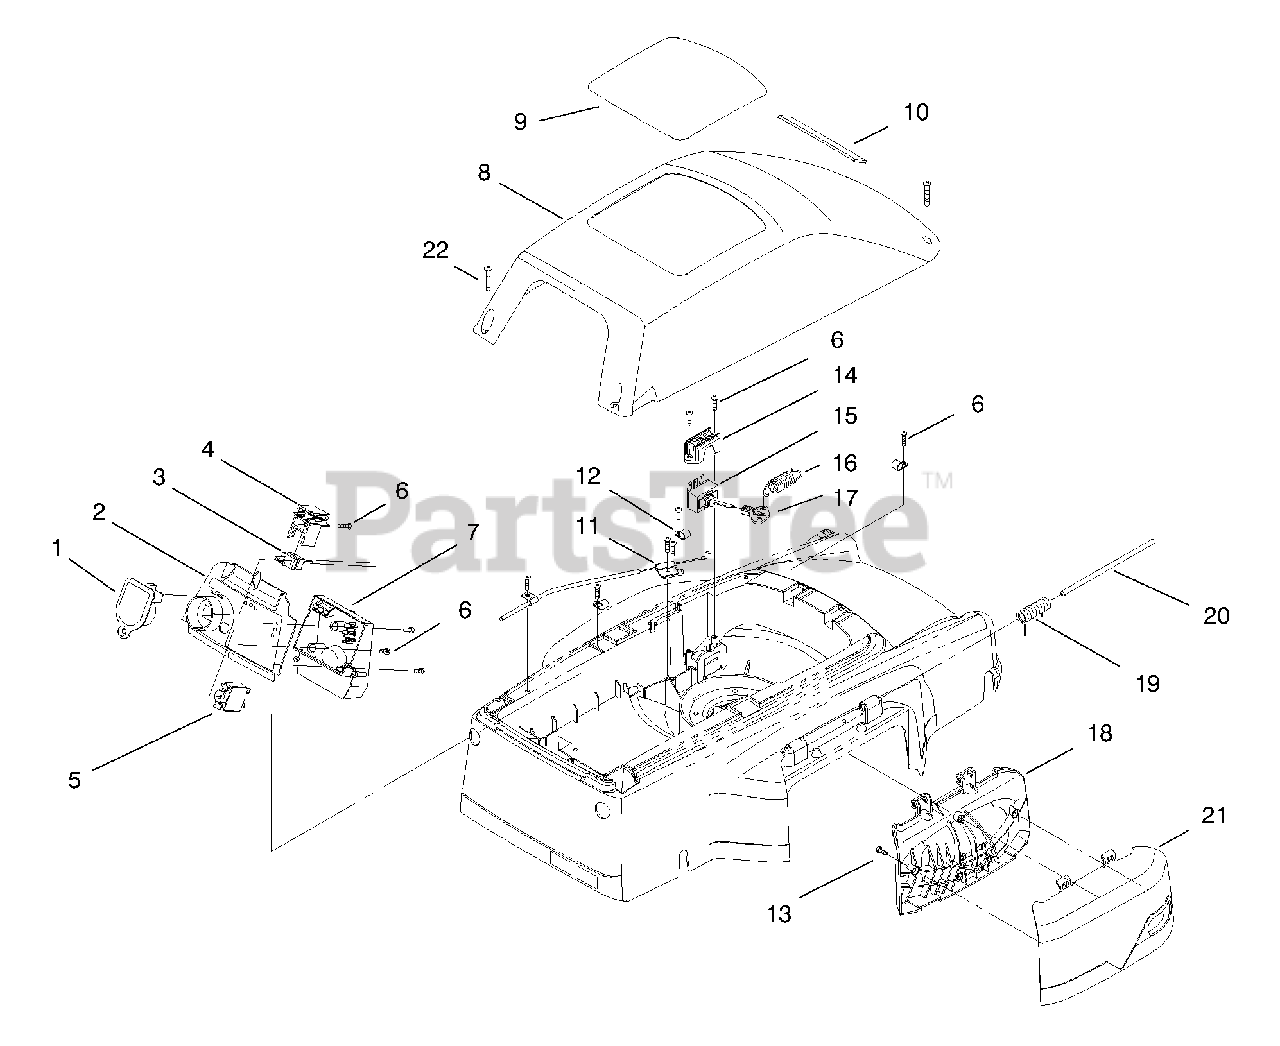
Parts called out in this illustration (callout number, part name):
2	ASM-Panel
3	ASM-Plug
4	Housing-Plug
5	Circuit Breaker
7	ASM-Circuit Board
8	ASM-Cover
9	Decal-Cover
10	Applique-Shroud
11	Bracket-Cable
12	Clamp-Cable
14	Clamp-Switch
15	Switch-Toggle
16	Spring-Switch
17	Cover-Lever
18	Mulch Plug-Inside
19	Spring-Torsion
20	Pin-Hinge
21	Mulch Plug-Outside
22	Screw-PPH
